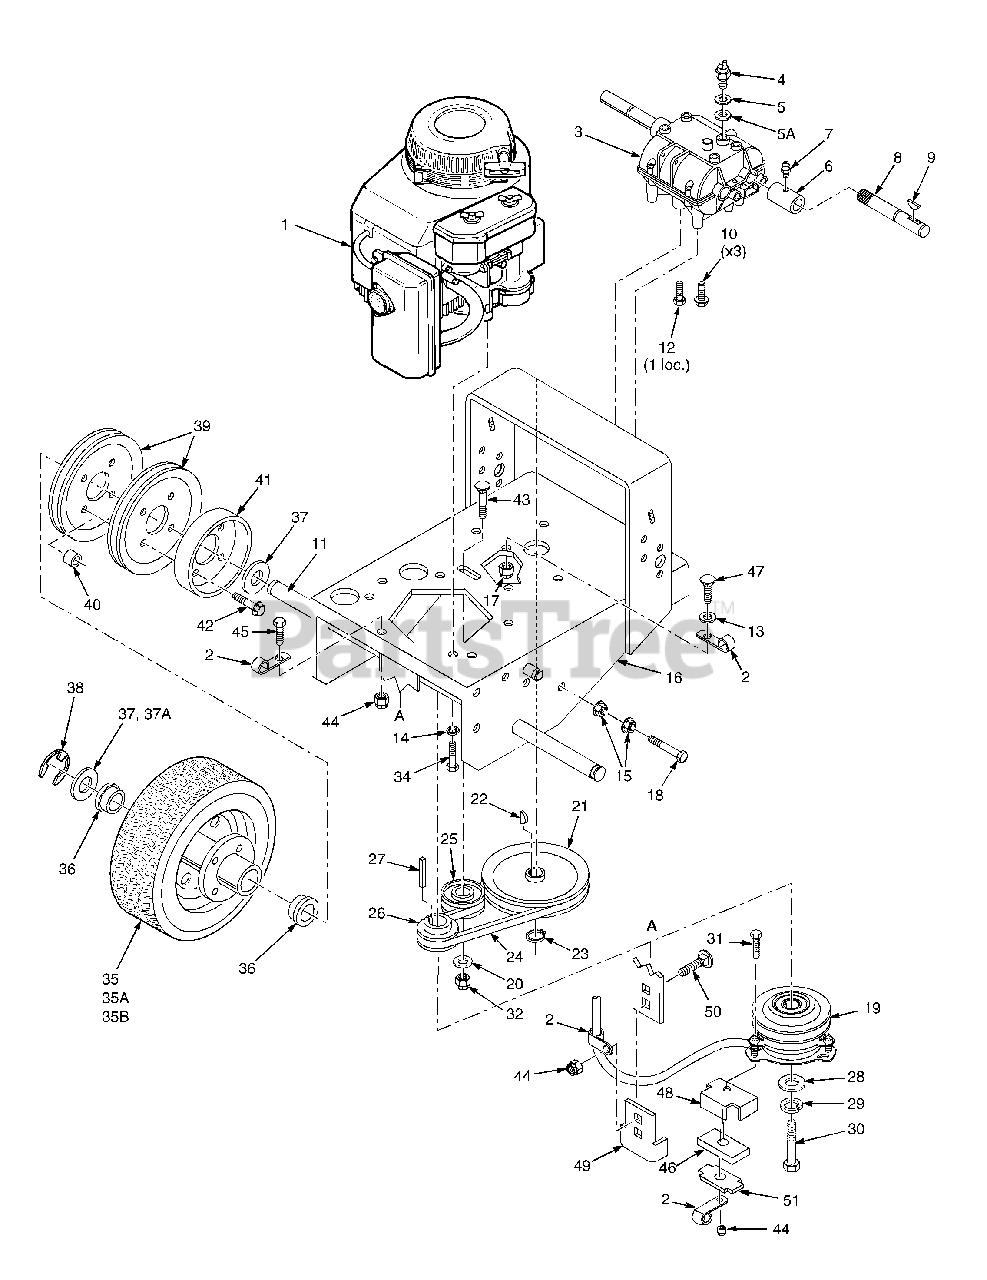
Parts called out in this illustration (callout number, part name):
1	Engine,18HP Kohler (CV493T, Spec PS-27526)
2	Cable Clamp
3	Transmission, 5-speed (Peerless 700-070, 9 tooth spline)
4	Neutral Safety Switch
5	Fibre Washer, thin
5A	Fibre Washer, thick
6	Coupler, Jackshaft
7	Grease Fitting, straight 1/4-28
8	Jackshaft
9	Key, Hi-Pro #9
10	Bolt, 5/16-18 X 3/4" Carriage
11	Wheel Axle
12	Bolt, 5/16-18 X 3/4" Hex Head
13	Flat Washer 1/4" (.312 X .75 X .065)
14	Lock Wshr. 5/16"
15	Nut, 3/8-16 Serrated Flange
16	Engine Deck
17	Nut, 1/4-20 Elastic Stop
18	Bolt, 3/8-16 x 3-3/4" Hex Head
19	Electric Clutch (Ogura)
20	Washer, 3/8" (.391 x .938 x .105)
21	Pulley, Transmission Input
22	Key, Woodruff #9
23	Retaining Ring, 5/8" Ext, Basic
24	Belt, Transmission Drive
25	Idler Pulley, Transmission
26	Pulley, Traction Drive
27	Key, 1/4 x 1/4 x 2-3/4"
28	Flat Washer, 7/16" Special
29	Lock Washer, 7/16"
30	Bolt, 7/16-20 x 2-1/2" Hex Head
31	Bolt, 5/16-18 x 1-3/4" Hex Head
32	Nut, 3/8-16 Elastic Stop
33	Flat Washer, 5/16"
34	Bolt, 5/16-18 x 1" Serrated Flange Hex Head
35	Wheel Assembly
35A	Tire, 13 x 6.50-6, 2-ply
35B	Rim & Bearing Assembly
36	Wheel Bearing (OD 2.000 - 2.005)
37	Washer, 1-1/16 x 1-3/4 x 12 ga
37A	Washer, 1-1/16 x 1-1/2 x 18 ga
38	Retaining Ring, 1" Ext.- "E"
39	Pulley, Wheel Drive
40	Spacer, Wheel Pulley
41	Brake Drum
42	Bolt, 5/16-18 x 1-1/2" Serrated flange
43	Bolt, 3/8-16 x 2" Carriage
44	Nut, 5/16-18 Elastic Stop
45	Bolt, 5/16-18 x 1" Hex Head
46	Rubber Pad, Clutch Stop
47	Bolt, 1/4-20 x 3/4" Carriage
48	Backing Plate
49	Anti Rotation Bracket
50	Bolt, 5/16-18 x 1" Carriage
51	Plate, Backing
